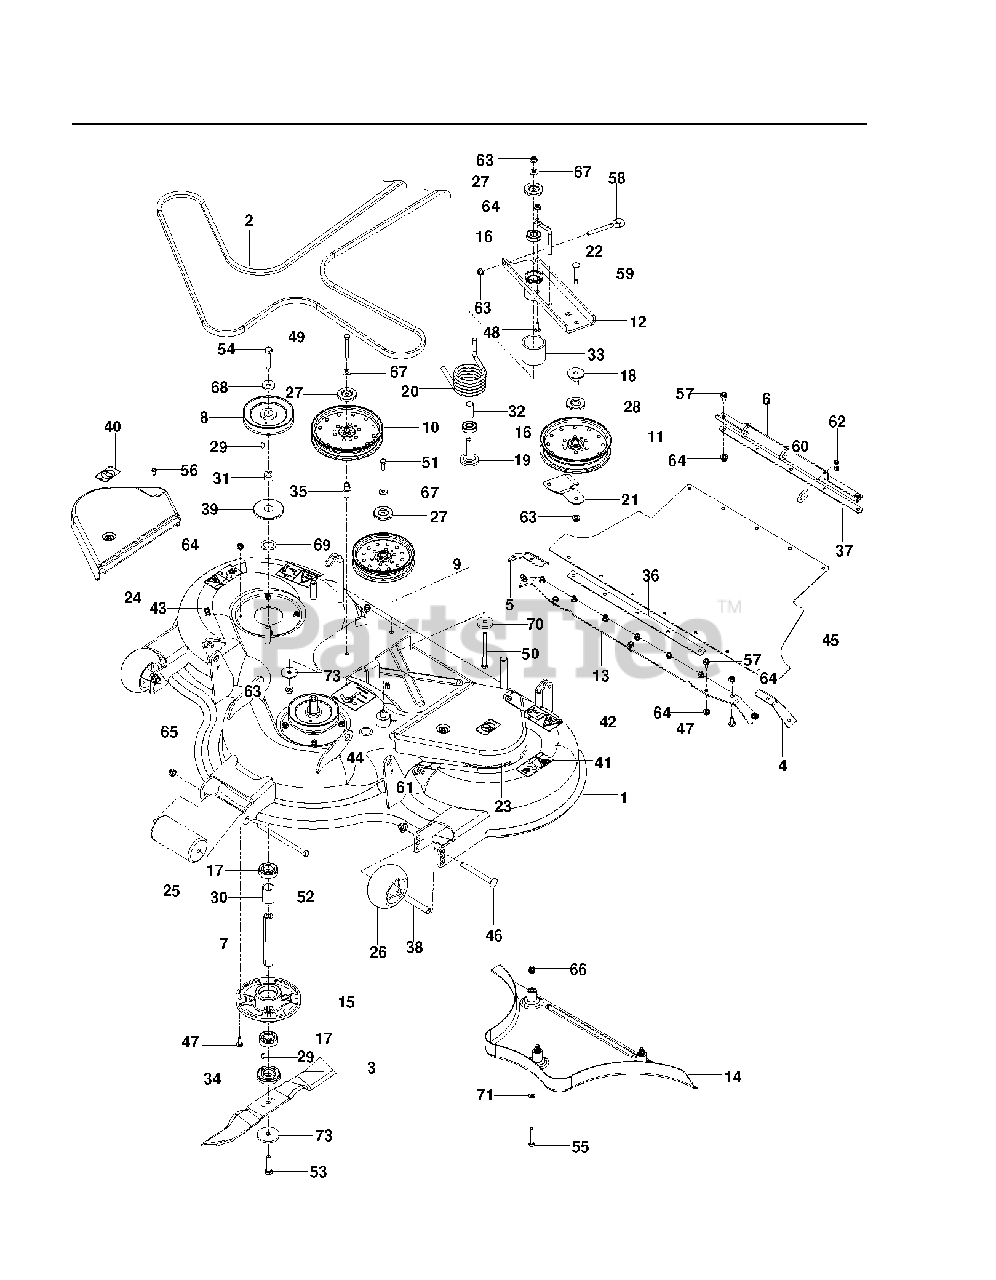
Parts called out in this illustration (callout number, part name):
3	BLADE
4	BRKT, L.H. CORNER BLK
5	BRKT, R.H. CORNER BLK
8	PULLEY, 52
9	PULLEY IDLER, 6" NARROW
10	PULLEY - 7" NARROW
11	PULLEY - IDLER 7"
12	IDLER.ARM.BLACK
15	BEARING HOUSING
16	BEARING, BALL
17	BALL BEARING
18	BEARING, IDLER ARM
19	BEARING, IDLER PIVOT
20	SPRING, TORSION, IDLER
21	BELT.GUIDE.BLACK
22	BELT KEEPER
23	BELT SHIELD LT
24	BELT SHIELD RT
25	ROLLER
26	ROLLER, GAUGE .635 BORN
27	DUST SHIELD
28	SHIELD, DUST
31	KEY RETAINER
32	SPACER, IDLER BEARINGS
33	SPACER, IDLER PIVOT
34	BUSHING, BLADE
35	IDLER BUSHING
37	STRAP, SHORT BLACK
38	TUBE, ROLLER AXLE
39	TOP DUST CAP
40	DECAL, NO STEP
41	DECAL, BELT DRIVE
42	DECAL, EURO SEVERING
43	DECAL, 132
44	DECAL, BELT ROUTING
46	RHSNB 1/2-13 X 4.75 GR5 ZD
47	RHSNB 5/16C X 1
48	RHSSNB 5/16C X 1.0
49	SCREW 3/8C X 2 3/4 HEX CAP
50	HCS 3/8-16 X 4-1/2 GR 8 ZD
51	HCS 3/8-16X1.GRD.5.ZD
52	HCS 7/16-14 X 7 GR5 ZD
53	HCS M12 X 1.75 X 50 GR8.8 ZD
54	HCS M12 X 1.75 X 60 GR5 ZD
55	HCS M8 X 1.25 X 50 GR8.8 ZD
56	SCREW 1/4 X 5/8
57	HHFS 5/16-18 X 3/4
58	EYE BOLT, 3/8 X 4"
59	CARRIAGE BOLT 3/8-16 X
61	NUT, 1/2-13 HEX FLG NYLOC ZD
62	RP_NUT 1/4-20 NYLOC
63	NUT 3/8-16 HEX FLG NYLOC ZD
64	5/16-18 NYLOC FLANGE NUT
65	NUT 7/16C CENTERLOCK
66	BLIND RIVET NUT
67	WASHER, 3/8 THICK
68	WASHER-.533IDX1.37OD
69	WASHER-1.06IDX1.63ODX.06
70	SPINDLE WASHER
71	FLAT WASHER 5/16 SAE
